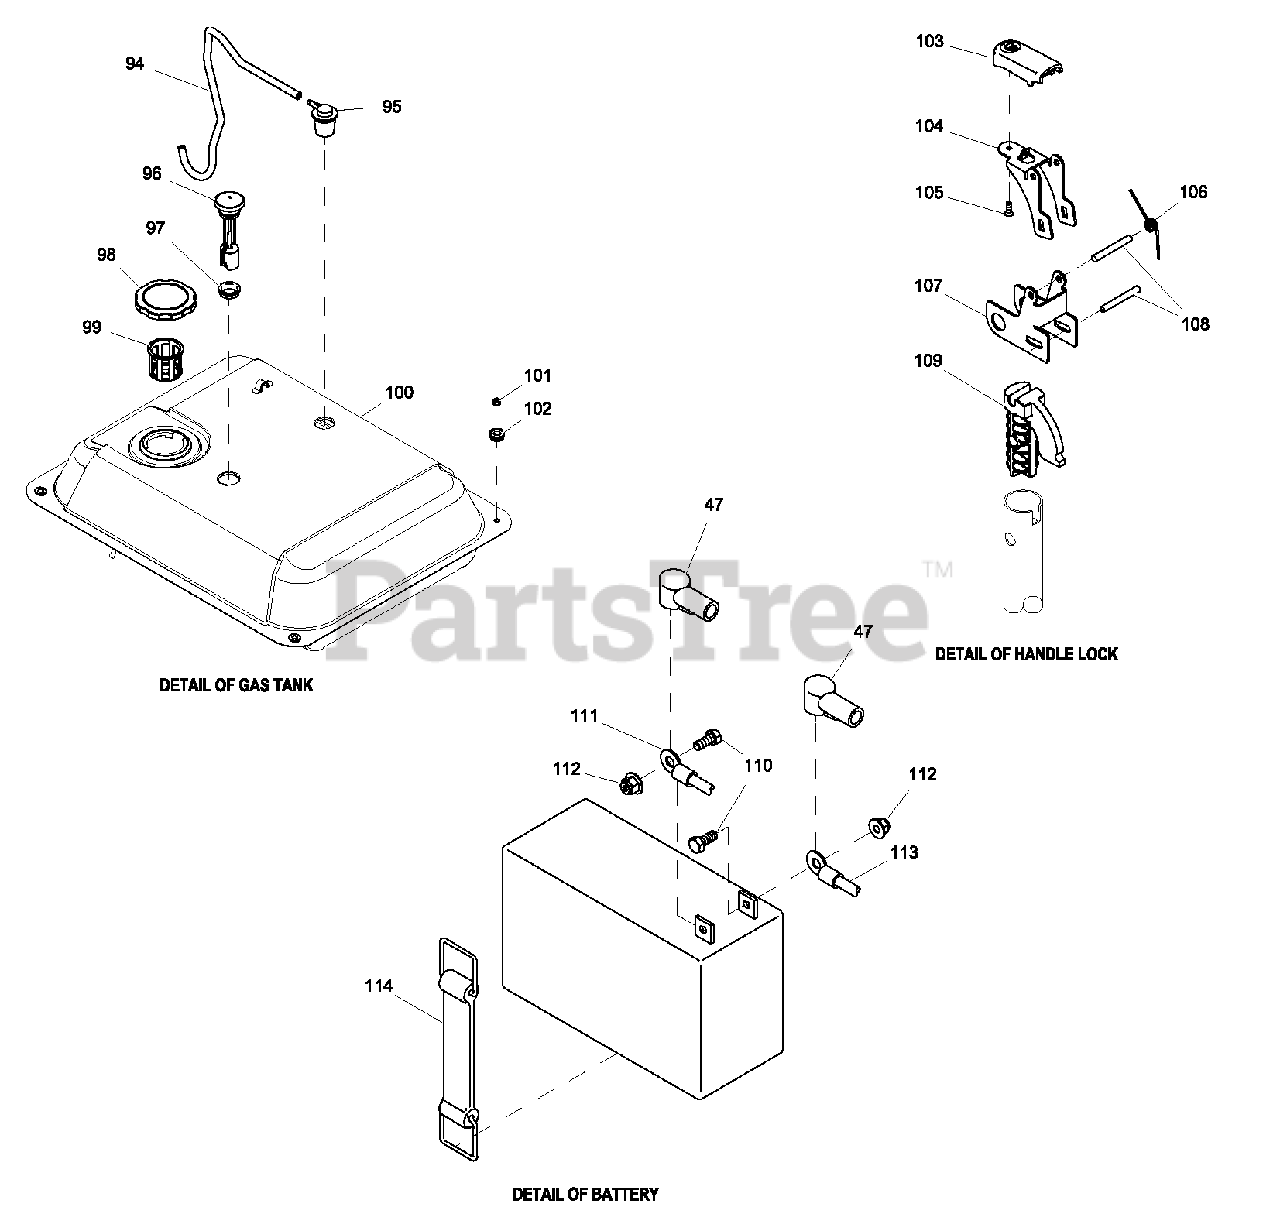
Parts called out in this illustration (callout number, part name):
94	HOSE 11MM OD X 5.5MM ID X 26IN
95	ASSY, ROLL OVER SLANT VALVE
96	FUEL GAUGE,ROUND 6.5" LONG
97	GROMMET FUEL GAUGE ROUND
98	ASSY GAS CAP SEALED - BLACK
99	FILTER, FUEL
100	WELDMENT FUEL TANK XP RAW CAL
101	INSERT, ANTI-CRUSH FOR TANKS
102	RUBBER MOUNT, 10.8 ID X 9 TALL
103	BUTTON LATCH RELEASE
104	LEVER, LATCH RELEASE
105	SCREW PFHP #8-16 X 1/2
106	SPRING TORSION, LATCH RELEASE
107	BRACKET, LATCH
108	PIVOT PIN, LATCH RELEASE
109	PLUG, FOLD DOWN HANDLE
110	SCREW HHC M5-0.8 X 12 C8.8
111	WIRE, #16 START SOL-STARTER XP
112	NUT FLANGE M5-0.8 NYLOCK
113	WIRE ASSY SOL TO BATT-POS
114	ASSEMBLY, BATTERY STRAP
